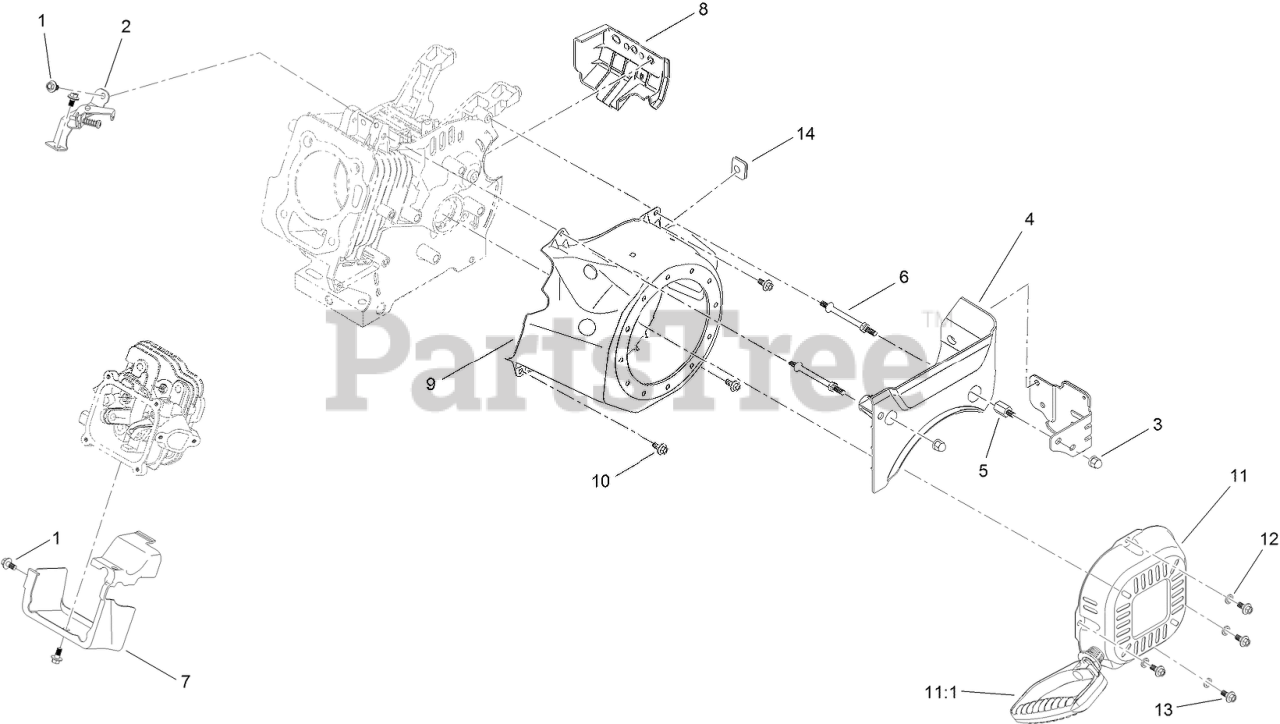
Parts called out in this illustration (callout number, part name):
1	SCREW-HHF
2	THROTTLE CONTROL ASM
3	NUT-ACORN
4	PANEL-FRONT
5	SPACER-STUD, THREADED
6	STUD-MOUNT
7	SHROUD-HEAD
8	PANEL-SIDE, ENGINE
9	SHROUD-FLYWHEEL
10	SCREW-HHF
11	RECOIL ASM
11:1	HANDLE-RECOIL
12	WASHER-PLAIN
13	SCREW-HHF
14	GROMMET-RUBBER
